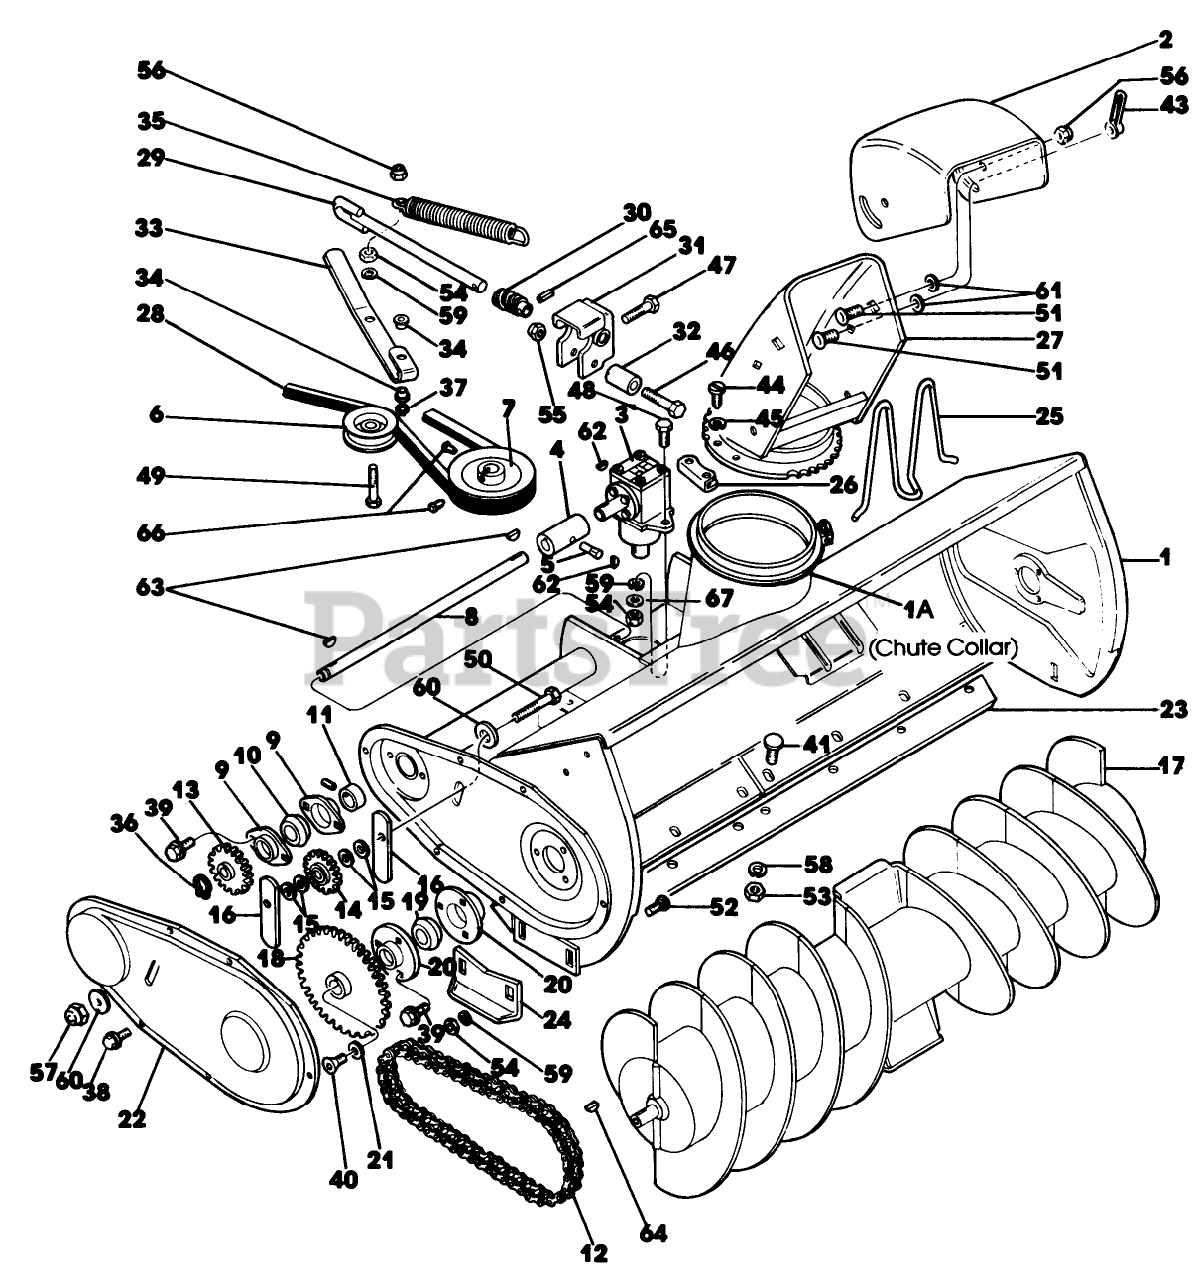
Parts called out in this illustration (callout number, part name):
24	Skid
31	Worm Support
58	Lock Washer 5/16 Plated
